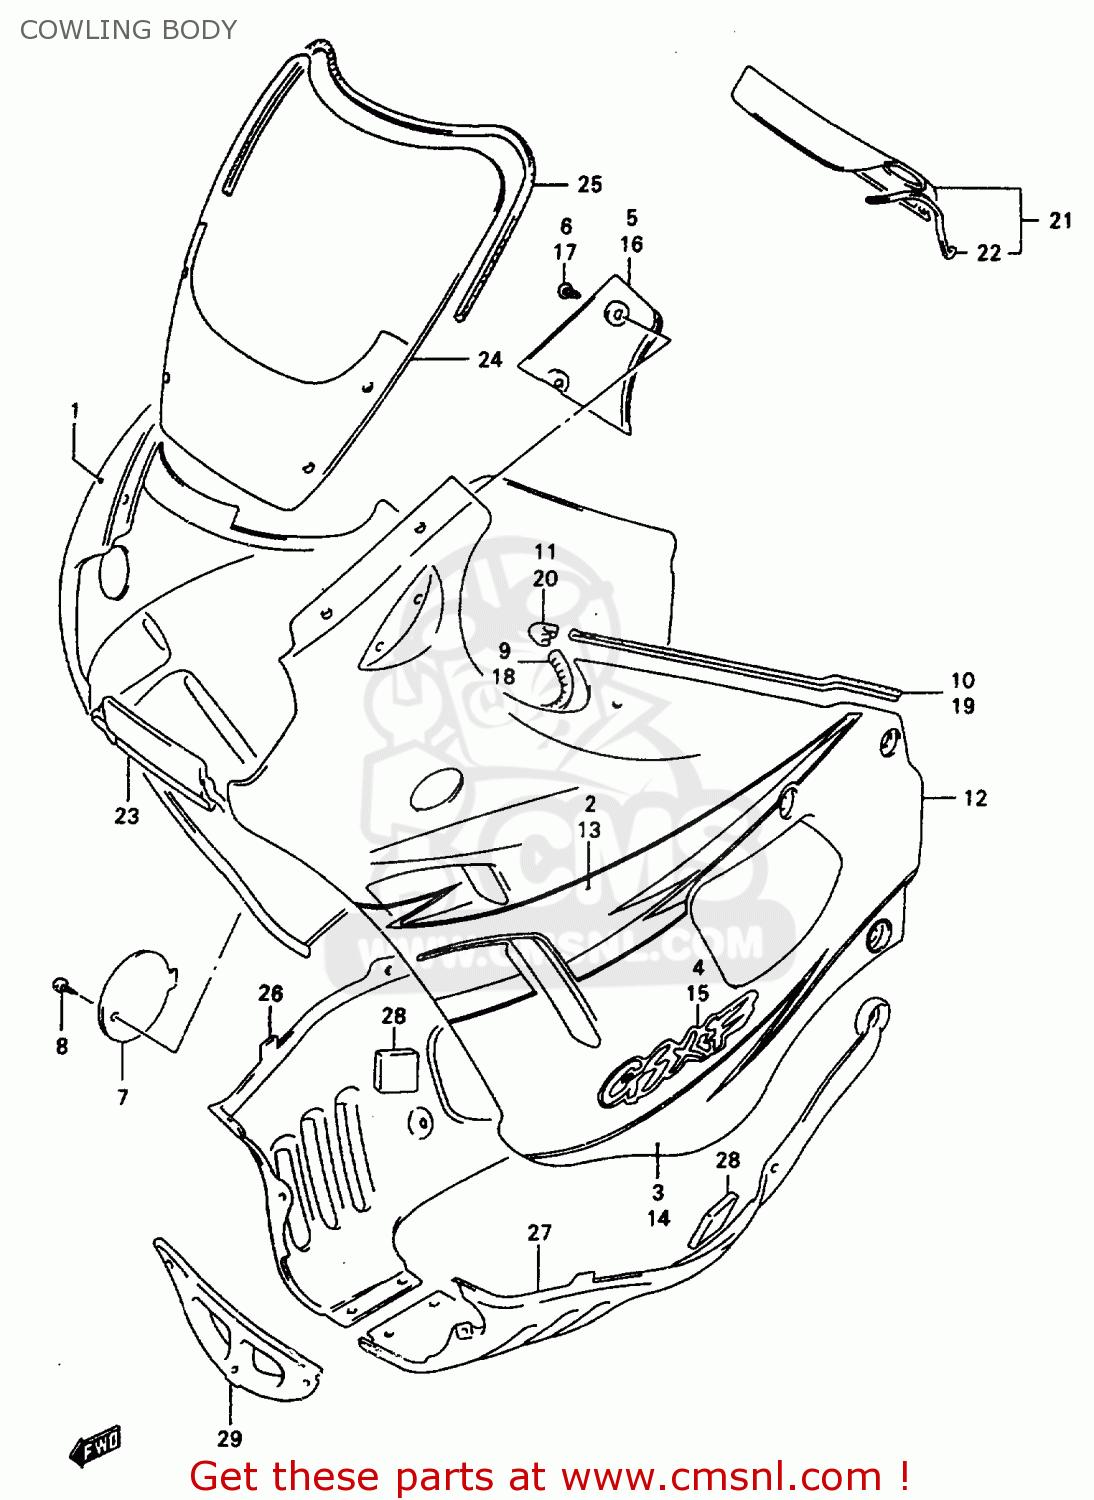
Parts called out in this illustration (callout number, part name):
1	COVER ASSY,COWLING,R
2	TAPE,BODY COWL SIDE UPR,R
3	TAPE,BODY COWL SIDE LWR,R
4	EMBLEM,BODY COWL SIDE
5	COVER,METER SIDE,R
6	SCREW
7	LID,OIL
8	SCREW(6X16)
9	MOLD,COWLING
10	MOLDING
11	JOINT,MOLDING END
12	COVER ASSY,COWLING,L
13	TAPE,BODY COWL SIDE UPR,L
14	TAPE,BODY COWL SIDE LWR,L
15	EMBLEM,BODY COWL SIDE
16	COVER,METER SIDE,L
17	SCREW
18	MOLD,COWLING
19	MOLDING
20	JOINT,MOLDING END
21	COVER,METER
22	MOLDING
23	PANEL,COWLING CTR
24	WINDOW,COWLING
25	MOLDING,WINDSCREEN
26	COVER,COWLING,UNDER,RIGHT
27	COVER,COWLING UNDER,L
28	CUSHION,UNDER COWLING
29	COVER,COWLING UNDER FR
